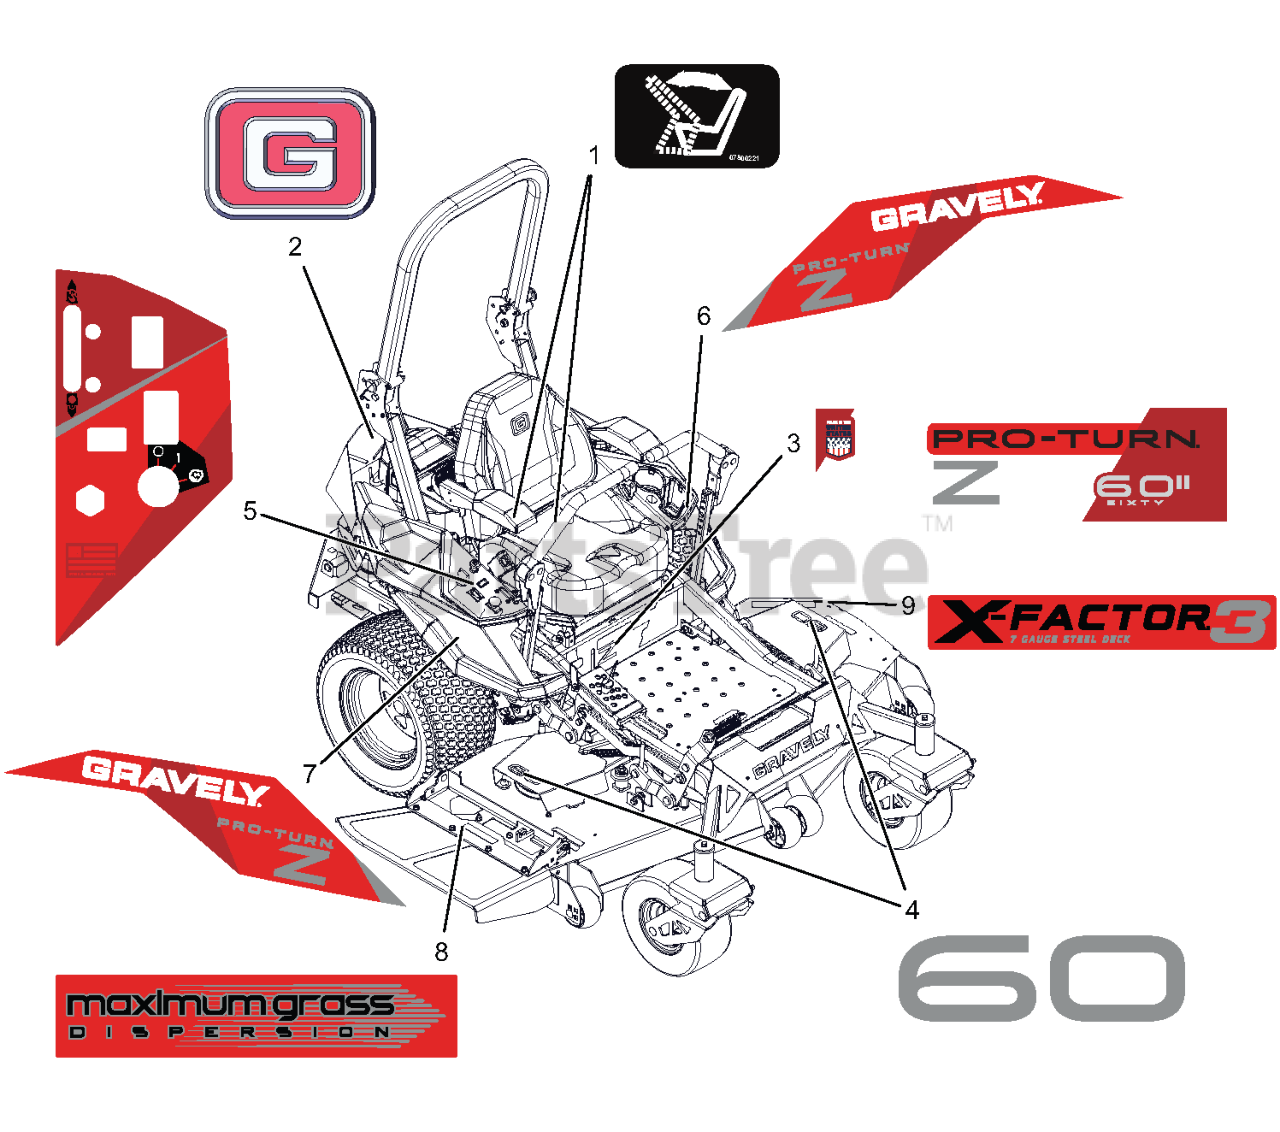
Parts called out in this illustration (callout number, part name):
1	DECAL - SEAT RELEASE
2	DECAL, GRAVELY BRAND
3	DECAL, PTZ - 60
4	DECAL, DECK - 60
5	DECAL, CONTROL PANEL
6	DECAL, FENDER LH - PTZ
7	DECAL, FENDER RH - PTZ
8	DECAL, DECK - MAX GRASS
9	DECAL, DECK - X-FACTOR 3 7 GAUGE
